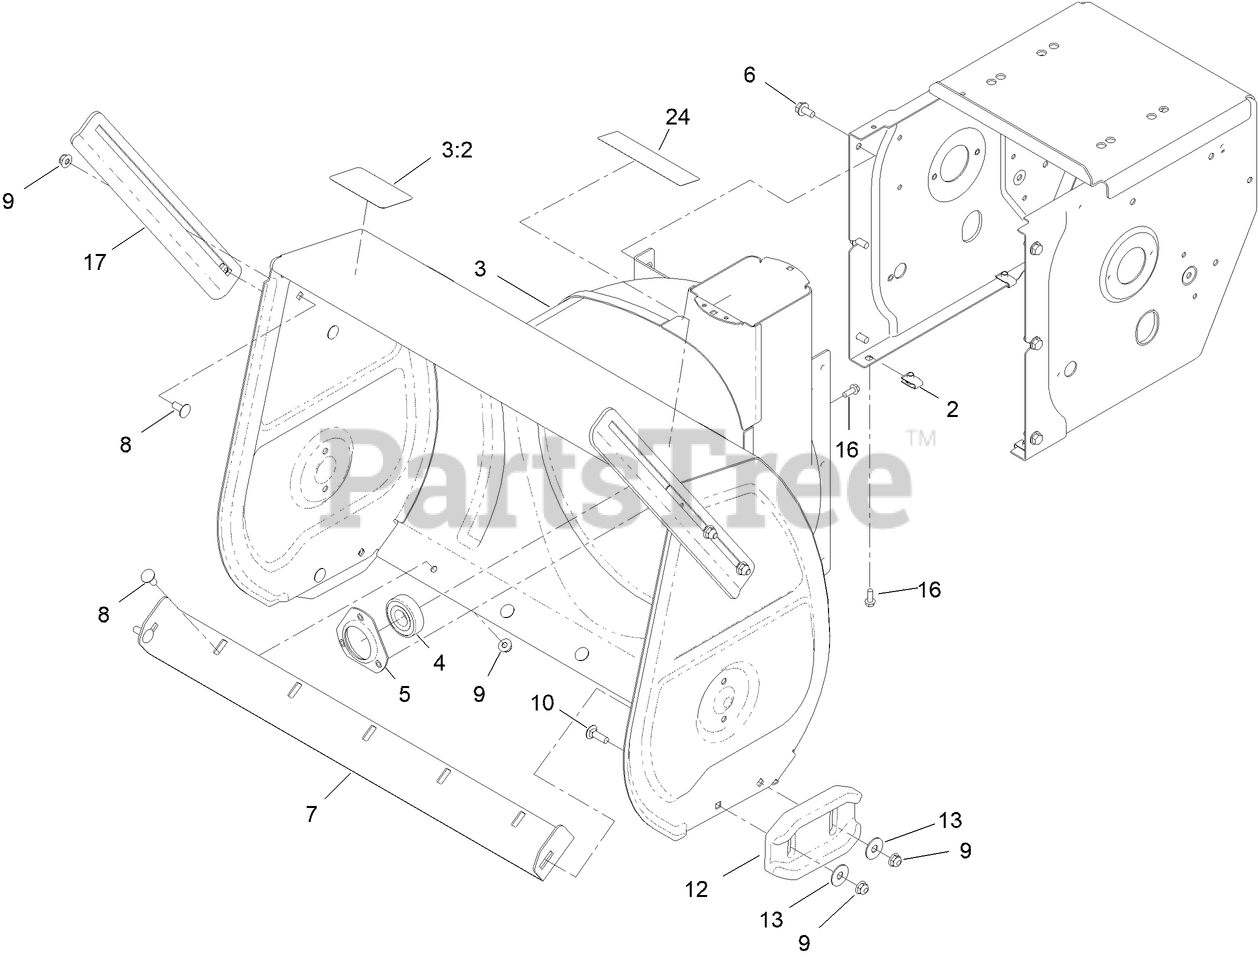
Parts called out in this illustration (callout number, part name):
3	AUGER HOUSING ASM
3:2	DECAL-DANGER, AUGER
4	BEARING-BALL
5	RETAINER-BEARING
6	SCREW-HWHTF
7	BLADE-SCRAPER
8	BOLT-CARR
9	NUT-HF
10	BOLT-CARR
12	SKID-CAST
13	WASHER-FLAT
16	SCREW-HWH
17	BREAKER-DRIFT, SIDE
24	DECAL - HEAVY DUTY 32
